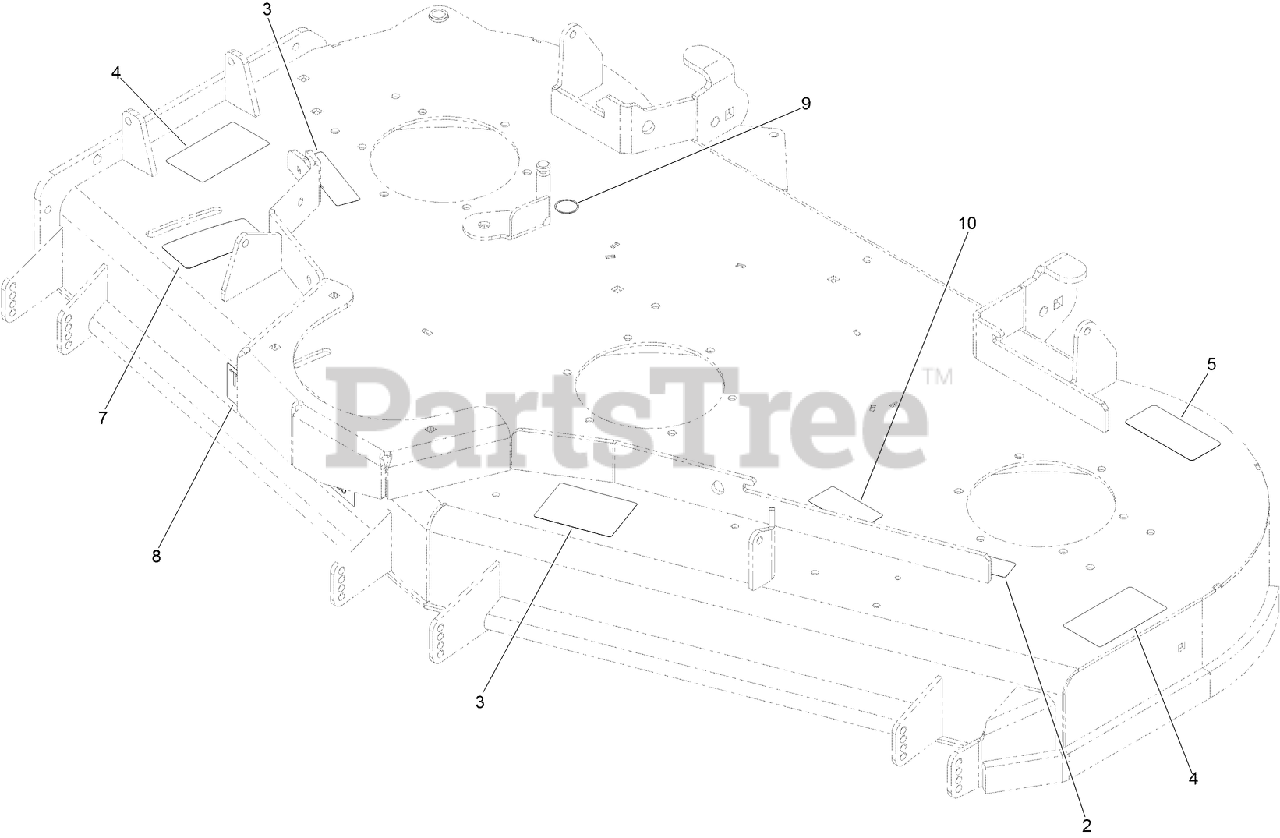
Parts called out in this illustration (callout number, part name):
2	DECAL-COVER, MISSING
3	DECAL-SCALP, ANTI
4	DECAL-DANGER THROWN OBJECTS
5	DECAL-TORQUE, BLADE BOLT
7	DECAL-ADJUSTMENT, BAFFLE
9	DECAL-GREASE
10	DECAL-BELT 60 SIDE
